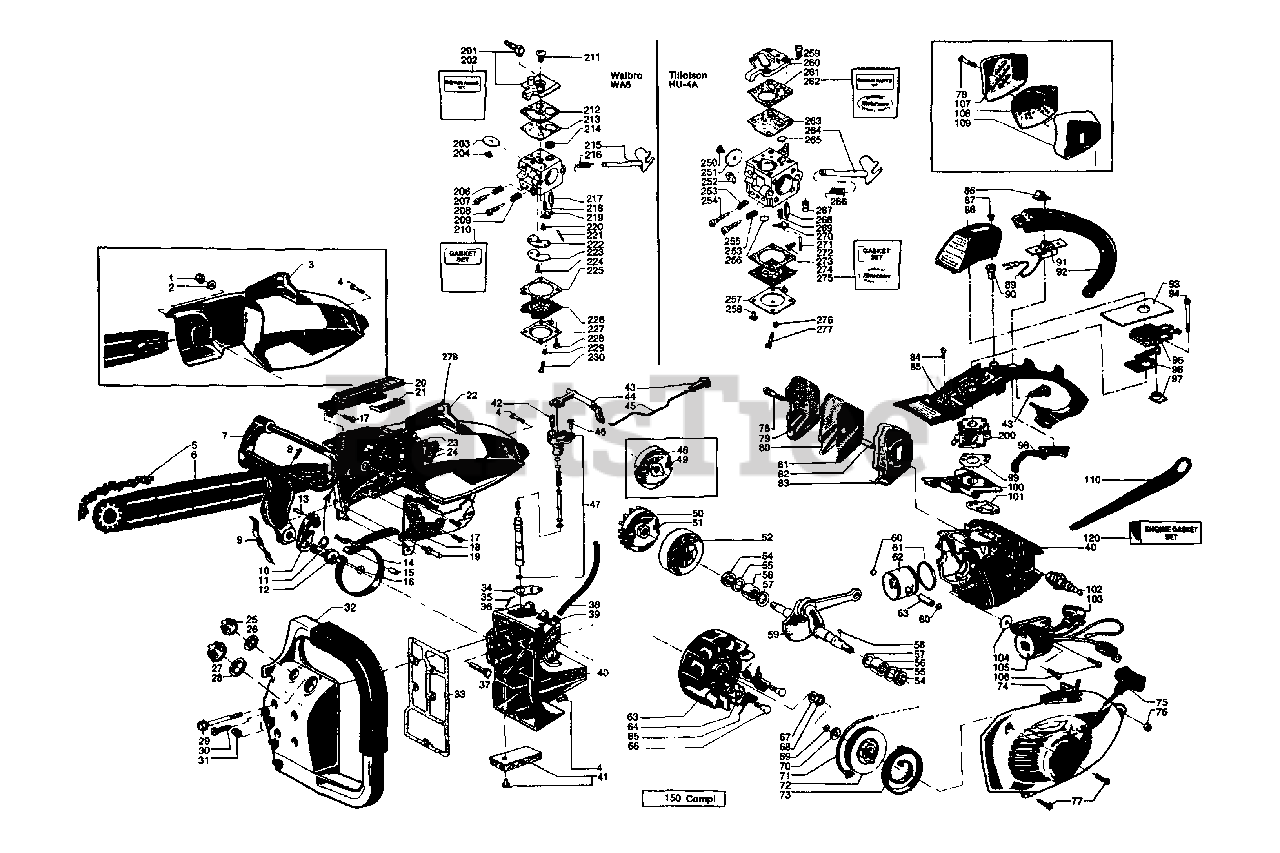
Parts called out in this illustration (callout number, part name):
2	WASHER
3	CLUTCH COVER
4	SCREW
6	BAR 12 '' 3/8''
9	SPRING NLA
12	HAND GUARD SHAFT NLA
14	BRAKE BAND
18	PROTECTION PLATE
19	CHAIN CATCHER
24	COVER PLATE
25	OIL TANK CAP
27	FUEL TANK CAP
30	REPL BY 505 80 00-92
32	TANK & HANDLE
40	CYLINDER & CRANKCASE
43	OIL PUMP BUTTON
44	CROSS SHAFT
45	PUSH ROD NLA
47	OIL PUMP ASSY NLA
48	REPL BY 504 35 07-90
62	REPL BY 504 35 08-89
74	FAN CASING
79	MUFFLER COVER
80	SPARK ARRESTOR
81	MUFFLER BAFFLE
83	MUFFLER BODY
86	TOGGLE CAP NLA
88	INTAKE COVER NLA
89	LEAD WIRE NLA
90	THREAD INSERT NLA
91	SWITCH NLA
92	HANDLE FILLER NLA
95	CHOKE HOLDER
98	THROTTLE TRIGGER
99	GASKET NLA
100	INSUL.FLANGE
103	IGNITION LEAD
104	WASHER NLA
107	MUFFLER COVER NLA
108	BAFFLE NLA
109	MUFFLER BODY NLA
110	SOCKET WRENCH NLA
120	GASKET SET NLA
200	CARBURETOR NLA
201	PUMP COVER
202	REPAIR PARTS KIT
203	THROTTLE FLAP
208	ADJ.SCREW H NLA
210	DIAPHRAGM SET
212	GASKET, FUEL PUMP
213	FUEL PUMP DIAPHRAGM
214	SCREEN
215	THROTTLE SHAFT
216	SPRING, THROTTLE RETURN
217	INLET NEEDLE
218	LEVER SPRING
221	FULCRUM PIN
222	GSKT
225	GASKET, METERING SIDE
226	DIAPHRAGM
227	DIAPHRAGM COVER
228	SCREW
229	PRESSURE SPRING NLA
230	IDLE SPEED SCREW
250	SCREW
251	THROTTLE FLAP
255	ADJ.SCREW HIGH SPEED NLA
256	WELCH PLUG
257	REPL BY 501 71 28-01
258	REPL BY 503 48 63-01
260	FUEL PUMP COVER
261	GASKET, PUMP SIDE
262	REPAIR PARTS KIT NLA
263	FUEL PUMP DIAPHRAGM
264	THROTTLE SHAFT
265	FILTER
268	INLET NEEDLE
273	GASKET, METERING SIDE
274	METERING DIAPHRAGM
276	METERING DIAPHRAGM
